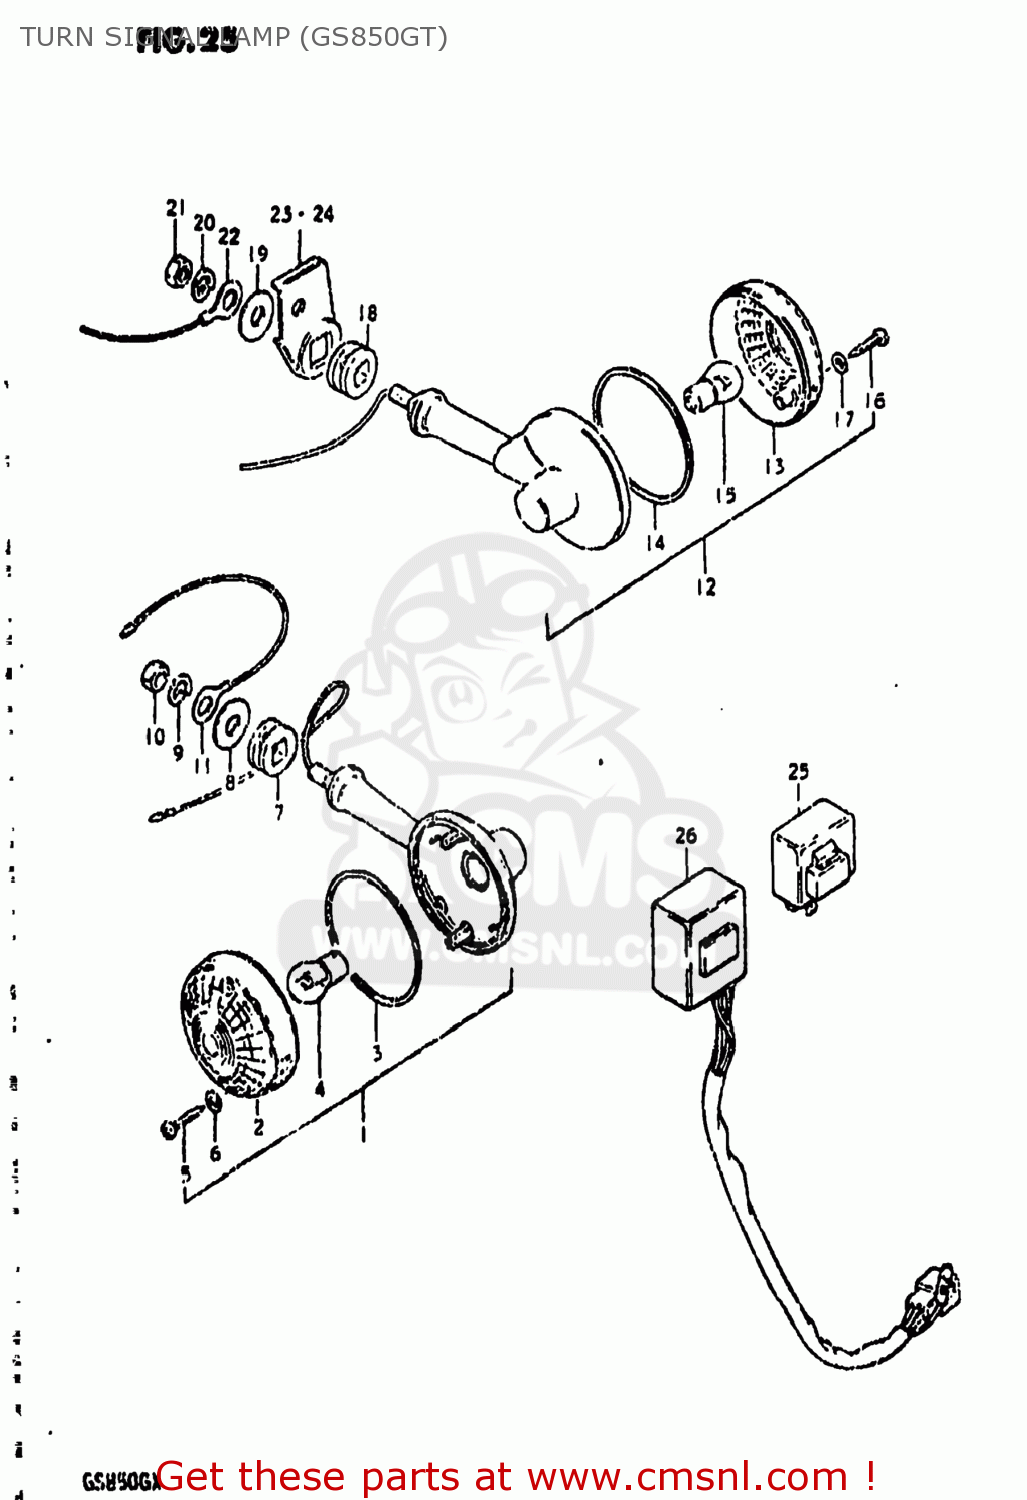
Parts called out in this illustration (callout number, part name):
1	LAMP ASSEMBLY,FRONT TURN SIGNAL
2	LENS
3	GASKET (NAS)
4	BULB(12V23W,STANLEY,A4577A)
5	BOLT
6	GASKET (NAS)
7	CUSHION
8	WASHER
9	LOCK WASHER
10	NUT
11	LEAD WIRE,EARTH
12	LAMP ASSEMBLY,FRONT TURN SIGNAL
13	LENS
14	GASKET (NAS)
15	BULB(12V23W,STANLEY,A4577A)
16	BOLT
17	GASKET (NAS)
18	CUSHION
19	SPACER (8.8X12X11)
20	LOCK WASHER
21	NUT
22	LEAD WIRE,EARTH
23	BRACKET,RR TURNSIGNAL LAMP,R
24	BRACKET,RR TURNSIGNAL LAMP,L
25	RELAY,TURN SIGNAL
26	UNIT,TURN SIGNAL CONTROL
